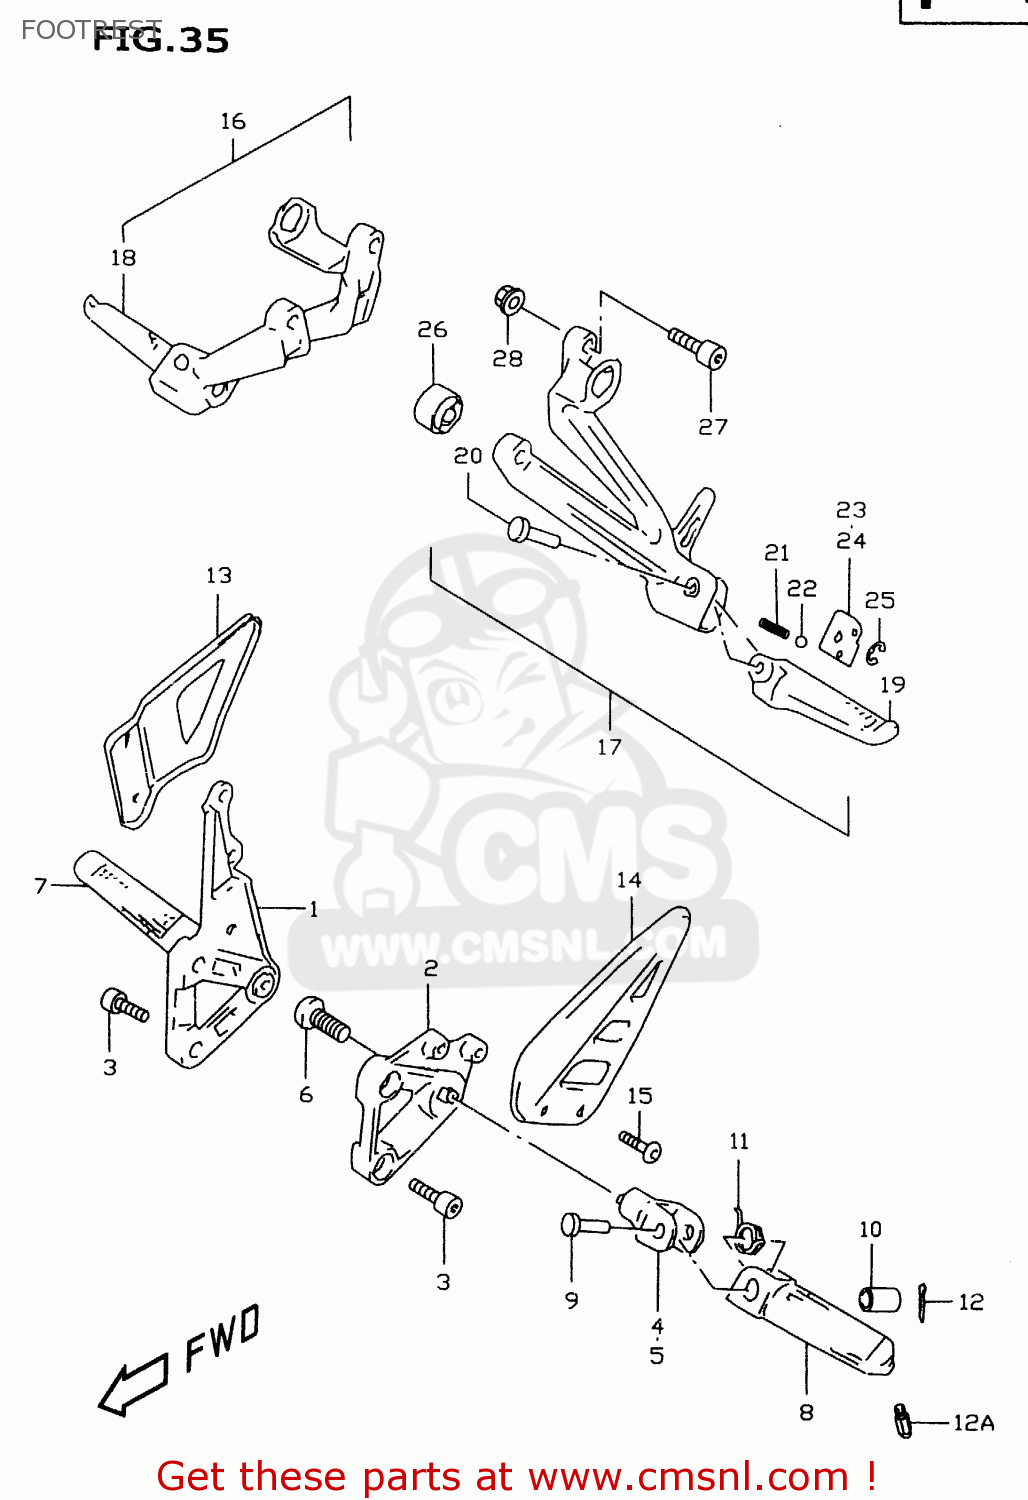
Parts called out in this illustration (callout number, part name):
1	BRACKET,FR FOOTREST,R
2	BRACKET,FR FOOTREST,L
3	BOLT
4	HOLDER,FOOTREST,R
5	HOLDER,FOOTREST,L
6	BOLT(10X28)
7	BAR,FOOTREST,RIGHT
8	BAR,FOOTREST,LEFT
9	PIN
10	SPACER(8.1X12X22)
11	SPRING
12	PIN 20X15
12A	BOLT,BANK SENSOR
13	GUARD,FR FOOTREST,R
14	GUARD,FR FOOTREST,L
15	SCREW(5X10)
16	FOOTREST ASSY,PILLION,R
17	FOOTREST ASSY,PILLION,L
18	BAR,PILLION FOOTREST,RIGHT
19	BAR,PILLION FOOTREST,LEFT
20	PIN
21	SPRING
22	BALL
23	PLATE,PILLION,RIGHT
24	PLATE,PILLION,LEFT
25	E-RING
26	BUSH
27	BOLT
28	NUT
